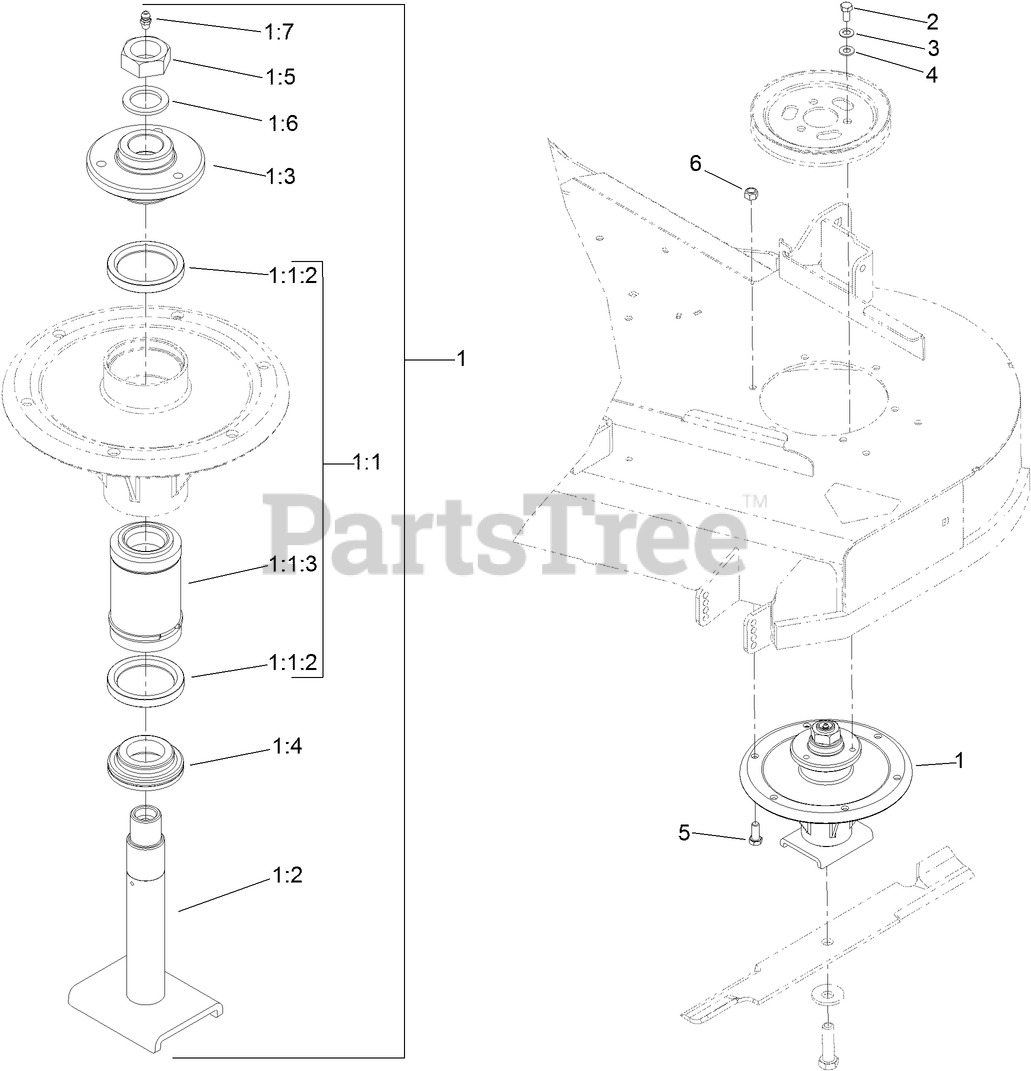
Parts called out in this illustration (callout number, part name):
1	SPINDLE ASM
1:1	SPINDLE BEARING ASM
1:1:2	SEAL-OIL
1:1:3	BEARING/SPACER KIT
1:2	SPINDLE SHAFT ASM
1:3	HUB-SPLINE
1:4	SPACER-SHAFT, SPINDLE
1:5	NUT-LOCK, NI
1:6	WASHER-THRUST
1:7	FITTING-GREASE
2	SCREW-HH
3	WASHER-BELLEVILLE
4	WASHER-FLAT
5	SCREW-HH
6	NUT-LOCK, NI
